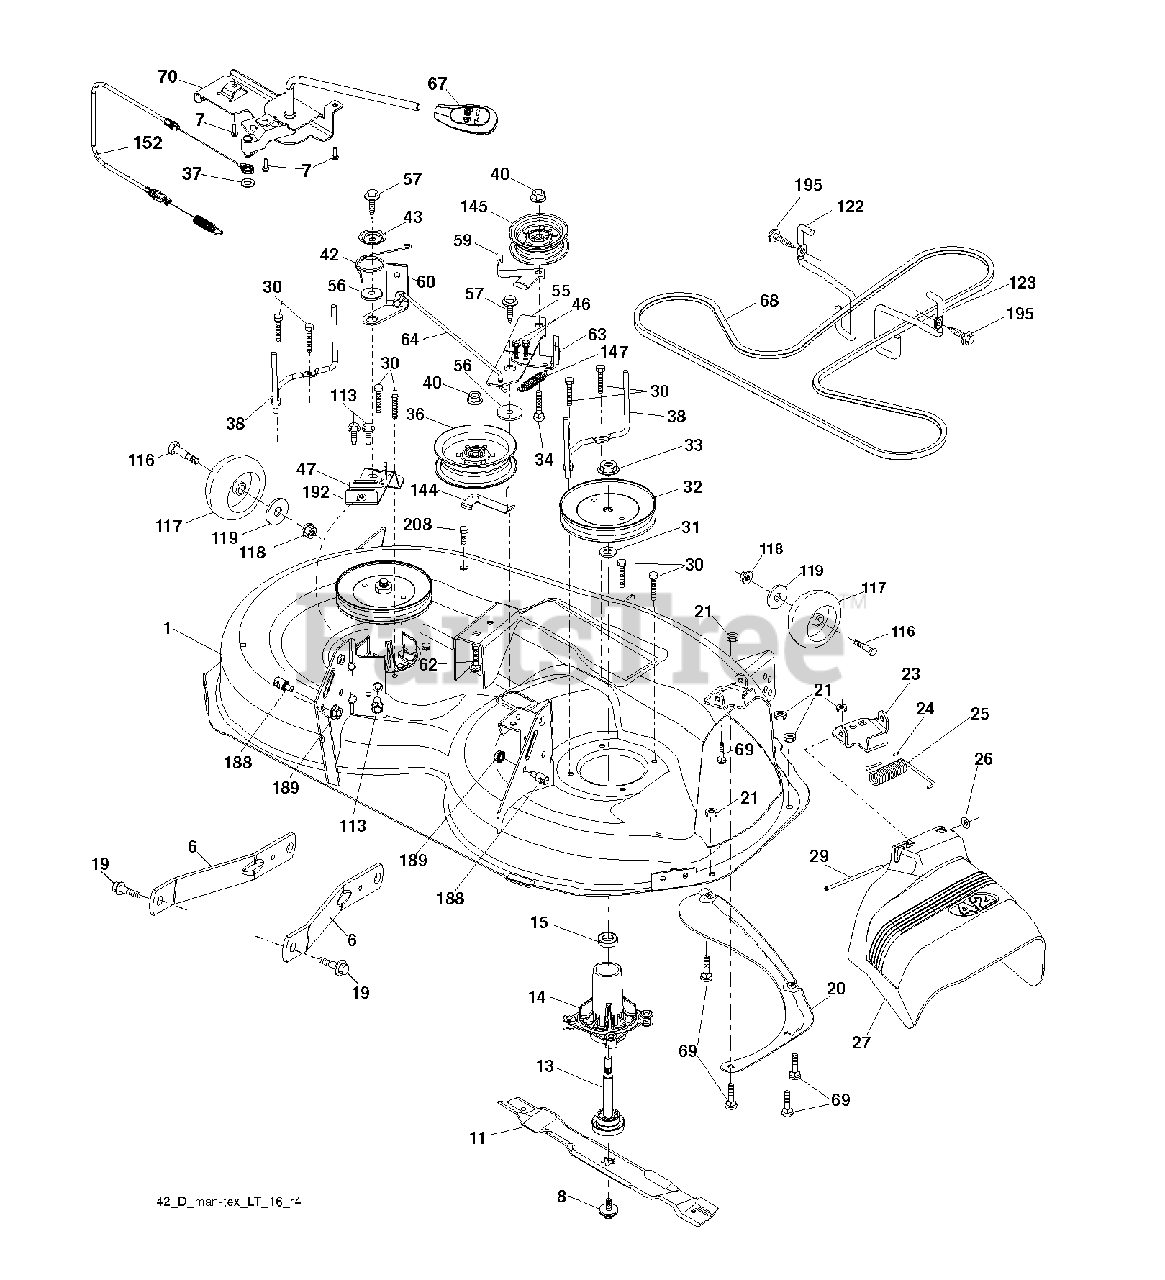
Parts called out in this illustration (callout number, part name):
6	ARM.SUSPENSION.MOWER.R
7	SCREW.#10 X 0.750.BOS (2 2)
8	BOLT.WASHER.ASM.7/16-2
11	42" HI-LIFT BLADE
13	SHAFT.ASM.MDRL.N/GREASE.38
14	HOUSING.MANDREL.4PT.
19	BOLT.SHOULDER
20	BAFFLE.VORTEX
21	LOCKNUT
23	BRKT.DEFLECTOR.38"2005+
24	CAP-SLEEVE LT
25	SPRING.TORSION.DEFLECT
26	NUT PUSH M
27	SHIELD.DEFLECTOR.MOWER.42"BLAC
29	ROD.HINGE
30	SCREW, WASHER HEAD
31	WASHER.SPACER.MANDREL
32	PULLEY.MANDREL.5.438.PD
33	NUT.FLANGE.LOCK.TOP
34	BOLT.3/8-16X1.50
36	PULLEY.IDLER.2006
38	KEEPER.BELT.MANDREL.PULLEY
40	NUT LOCK FLG 3/8-16 UNC
42	SPRING.TORSION.BRAKE
43	SRPING.TORSION.RETAINE
46	SCREW.1/4-20X5/8
47	BRKT.BRAKE.STAND.LH.
55	IDLER.ARM.42"
56	SPACER.RETAINER
57	SCREW 3/8-16X1
59	GUARD, BELT
60	ARM BRAKE MOWER
62	BOLT
64	LINK BRAKE
68	BELT.DECK.DRIVE.42"
69	BOLT
70	CLUTCH.ASM.MANUAL.LT.TEX
113	BOLT.5/16HEX.WHS.HD
116	BOLT M
117	WHEEL.GAGE.HALF.SPOKED
118	LOCKNUT
119	WASHER
122	KEEPER BELT ENGINE LH
123	KEEPER BELT RH
144	KEEPER.BELT.MOWER
145	PULLEY.IDLER.48"PRIMARY
147	RETURN SPRING
152	CLUTCH CABLE
188	STUD.FASTNER.W/ANTI-ROTATE
189	NUT LOCK HEX FLANGE 5/16-18
192	BRKT.CLUTCH.CABLE
195	SCREW, 3/8-16X3/4
208	SCREW 3/8-16X1/2
